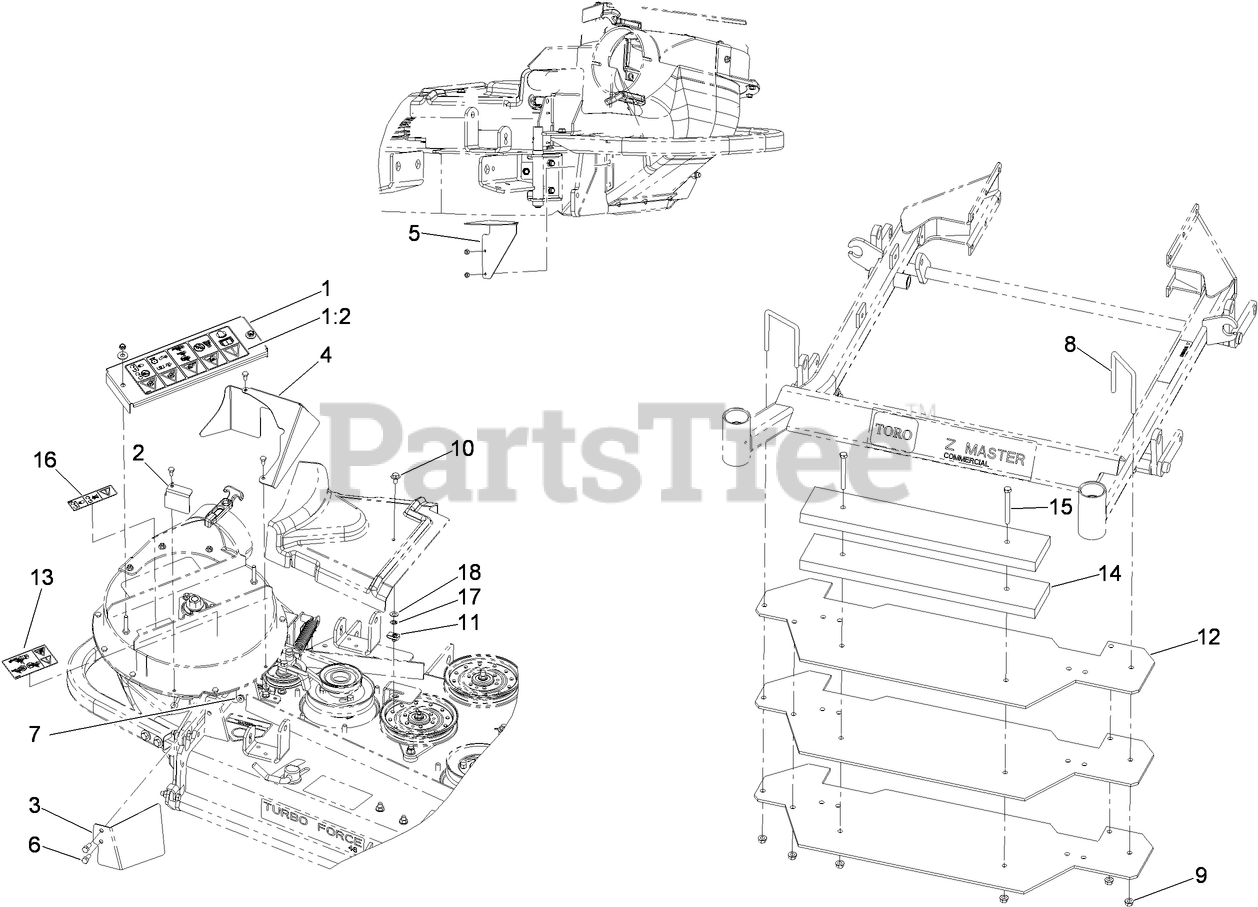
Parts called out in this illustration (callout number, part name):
1	COVER-BEARING
1:2	DECAL-DANGER
2	GUARD-LEFT
3	GUARD-FRONT
4	GUARD-BACK
5	GUARD-LOWER
6	SCREW-HH
7	NUT-HF
8	U-BOLT (4 INCH)
9	NUT-HF
10	SCREW-HHF
11	NUT-U
12	PLATE-WEIGHT
13	DECAL-WARNING
15	SCREW-HH
16	DECAL-COVER, MISSING
17	NUT-PUSH
18	WASHER-THRUST
